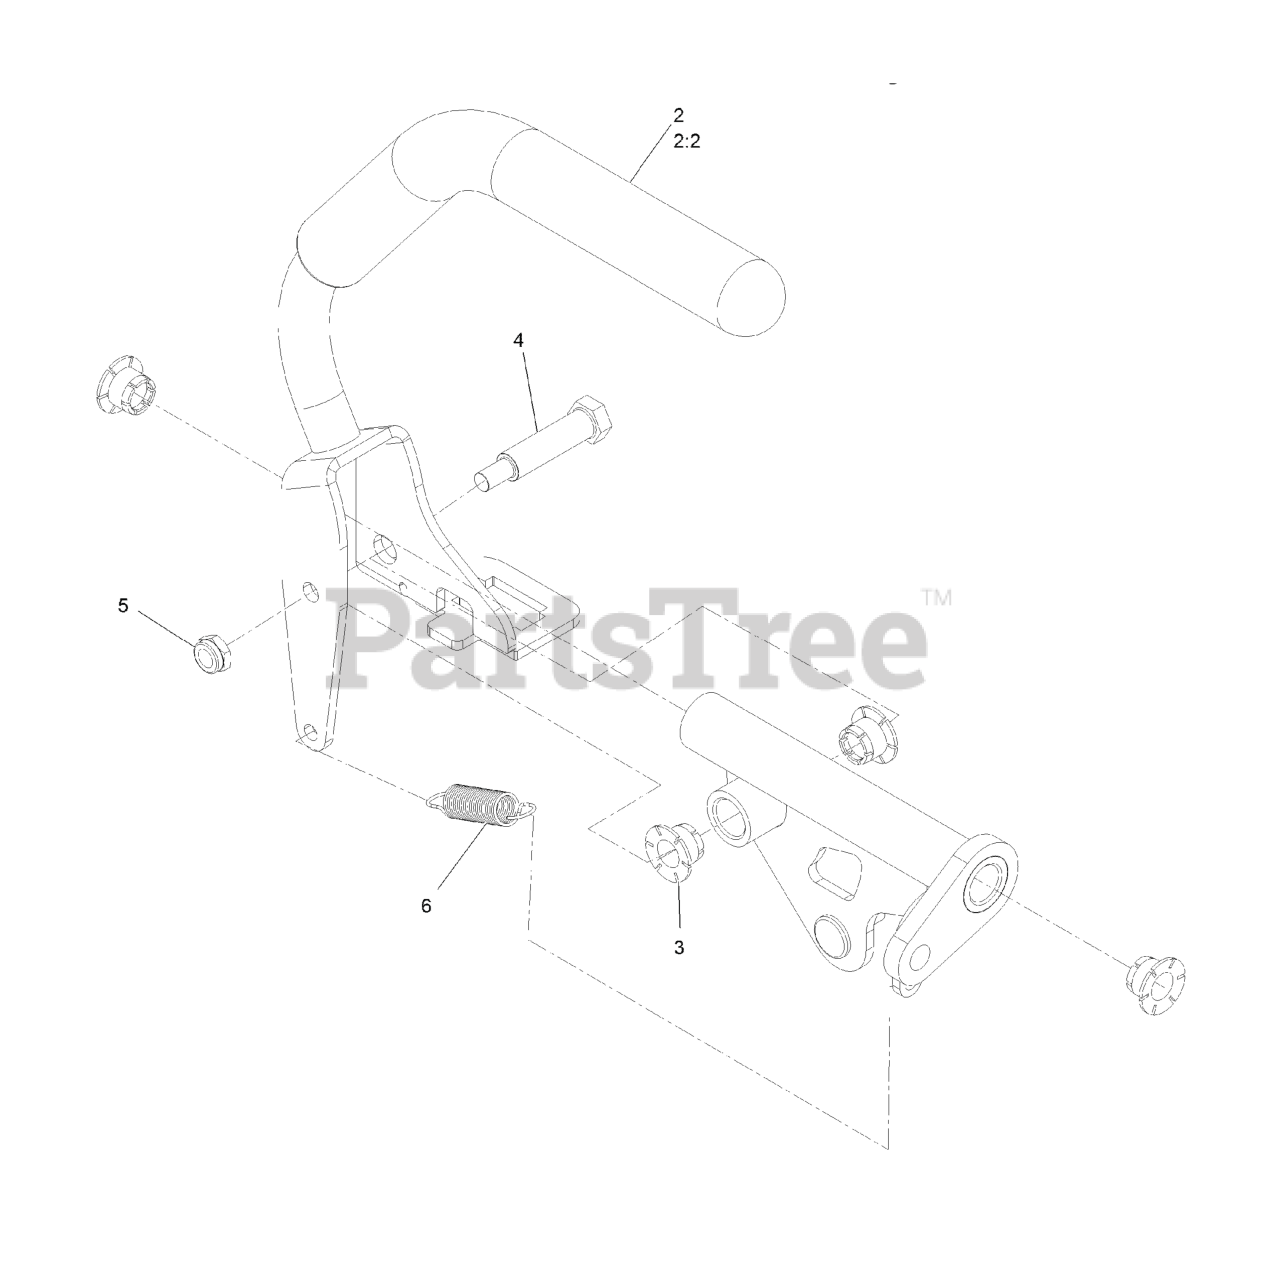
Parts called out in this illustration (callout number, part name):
2	ASM, LT CONTROL LEVER W/ GRIP
2:2	GRIP, DRIVE LEVER
3	BEARING, IGUS
4	BOLT-SHOULDER
5	NUT-LOCK, NI
6	SPRING-EXTENSION
